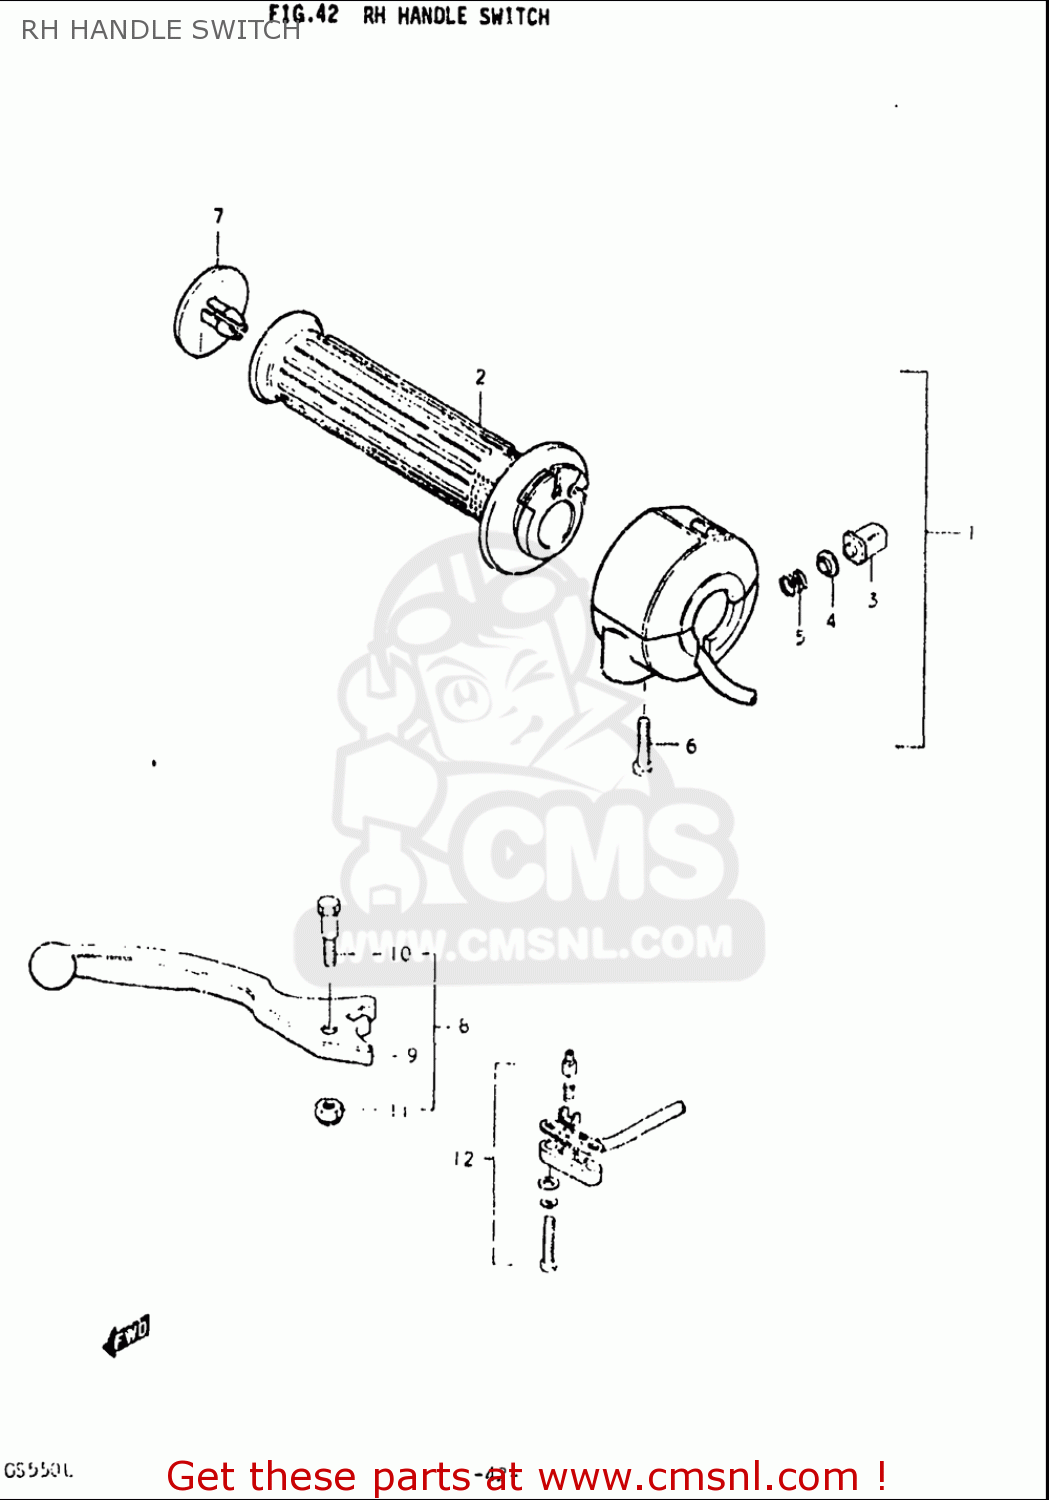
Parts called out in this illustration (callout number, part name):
1	CASE ASSY,THROTTLE
2	GRIP,THROTTLE
3	BUTTON,HORN
4	SPRING
6	SCREW
7	CAP,GRIP END
8	LEVER,BRAKE
9	LEVER,BRAKE
10	BOLT
11	NUT 6MM
12	SWITCH ASSY,STOP
